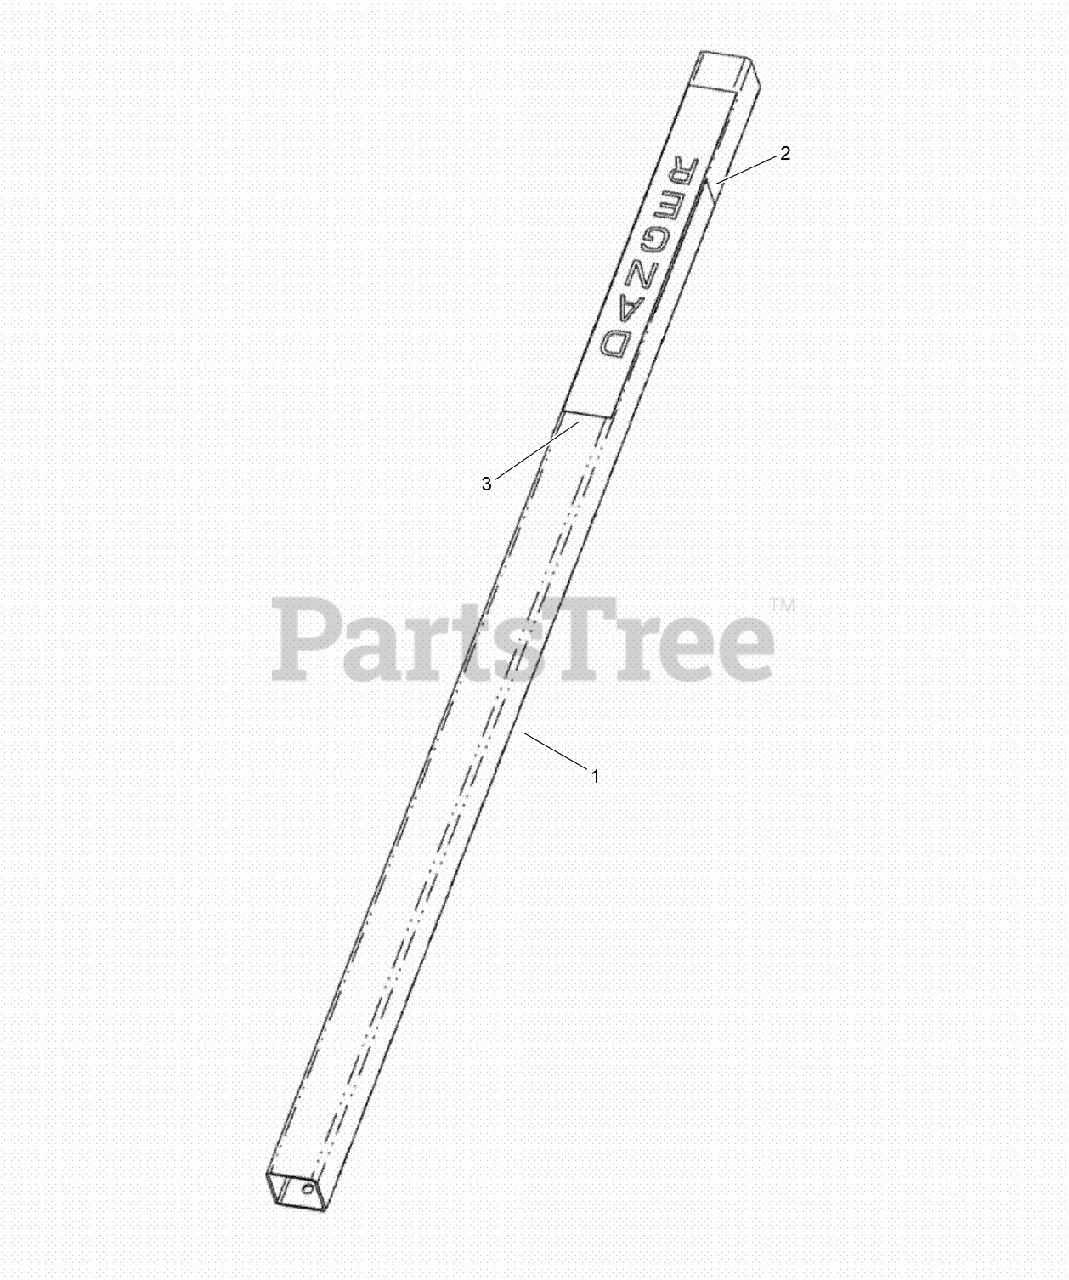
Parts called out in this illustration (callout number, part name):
1	TUBE-Restraint Bar
2	DECAL-Danger, Entanglement Hazard
3	DECAL-Danger
